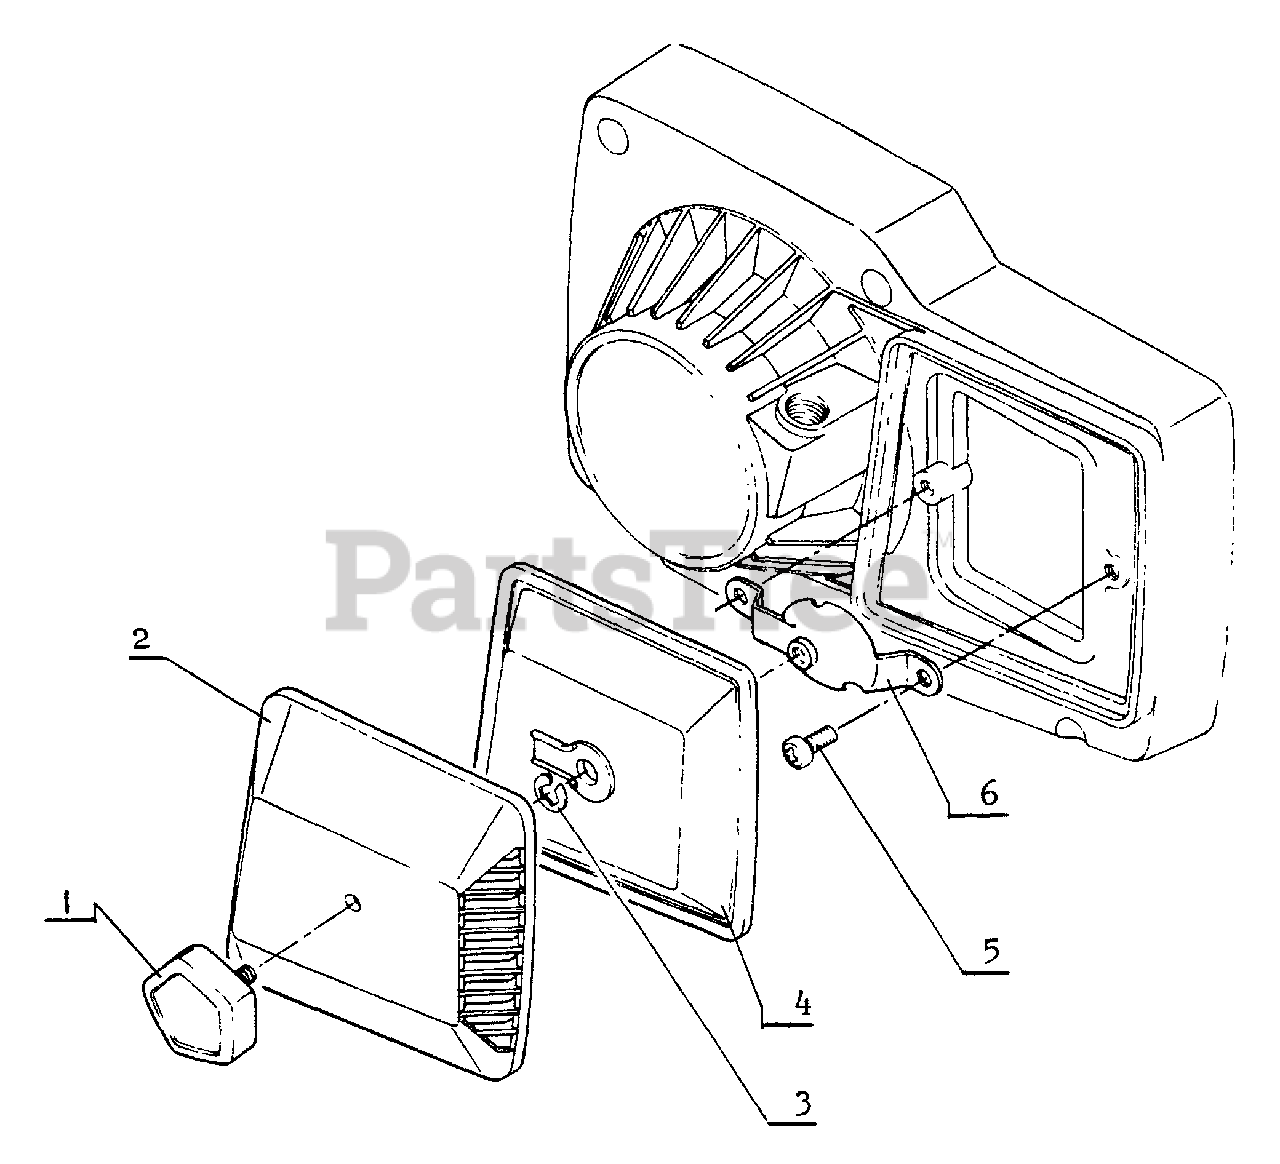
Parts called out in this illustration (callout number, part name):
1	THUMBSCREW
2	COVER, AIR FILTER
3	RING, RETAINING - 4
4	FILTER, AIR
5	SCREW - 5X10
6	PLATE, PREVENT
